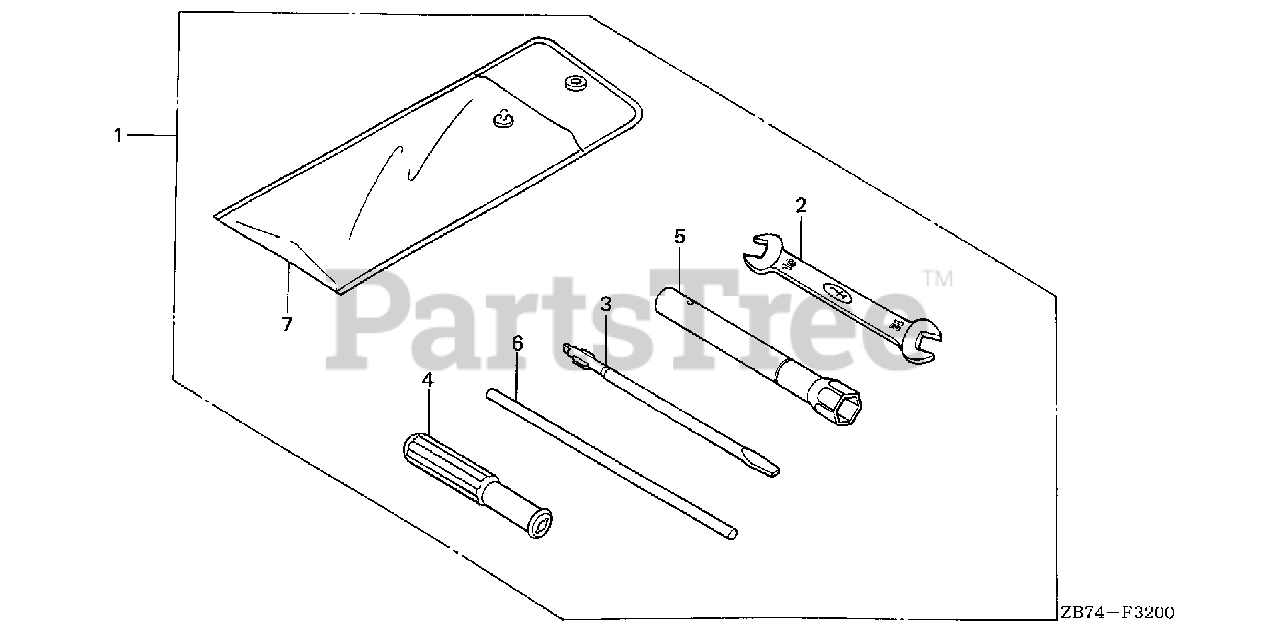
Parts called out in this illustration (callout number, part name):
1	TOOL KIT (N/A: SEE COMPONENTS)
2	SPANNER (10X12)
3	DRIVER 3, MINUS SCREW (NO.2)
4	GRIP, SCREW DRIVER
5	WRENCH, BOX (P21)
6	BAR A, HANDLE
7	BAG, TOOL
